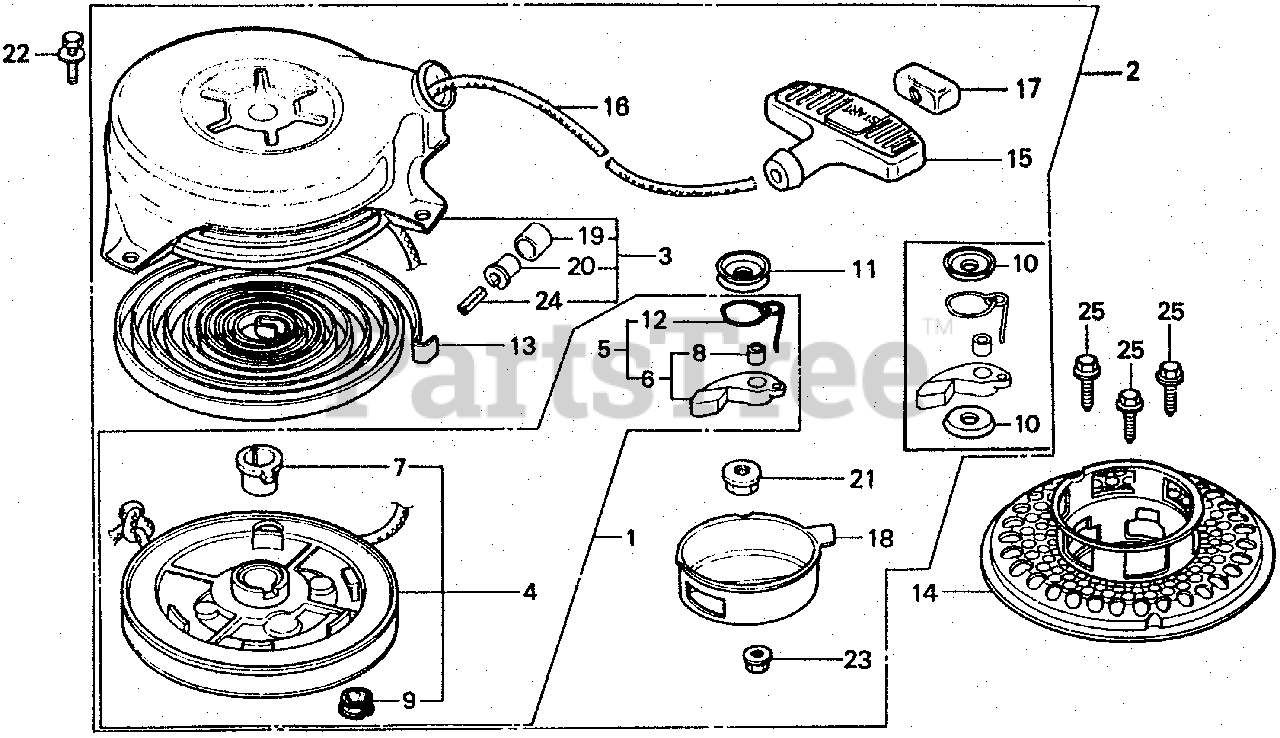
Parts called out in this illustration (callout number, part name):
1	REEL, STARTER
2	STARTER ASSY., RECOIL *R8* (BRIGHT RED)
3	CASE, STARTER *R8* (BRIGHT RED)
4	REEL, STARTER
5	RATCHET KIT
7	BOSS, REEL
8	BUSH, RATCHET
9	BUSH, REEL STARTER
10	PLATE, FRICTION
11	PLATE, FRICTION
12	SPRING, FRICTION
13	SPRING, RETURN
14	PULLEY, STARTER
15	GRIP, STARTER
16	ROPE, RECOIL STARTER (#5X55")
17	SUPPORT, GRIP
18	COVER, REEL STARTER
19	ROLLER, GUIDE
20	BUSH, ROLLER
21	NUT, SELF-LOCK (8MM)
22	BOLT-WASHER (6X10)
23	NUT, FLANGE (5MM)
24	PIN, SPRING (3X18)
25	BOLT, FLANGE (6X16)
